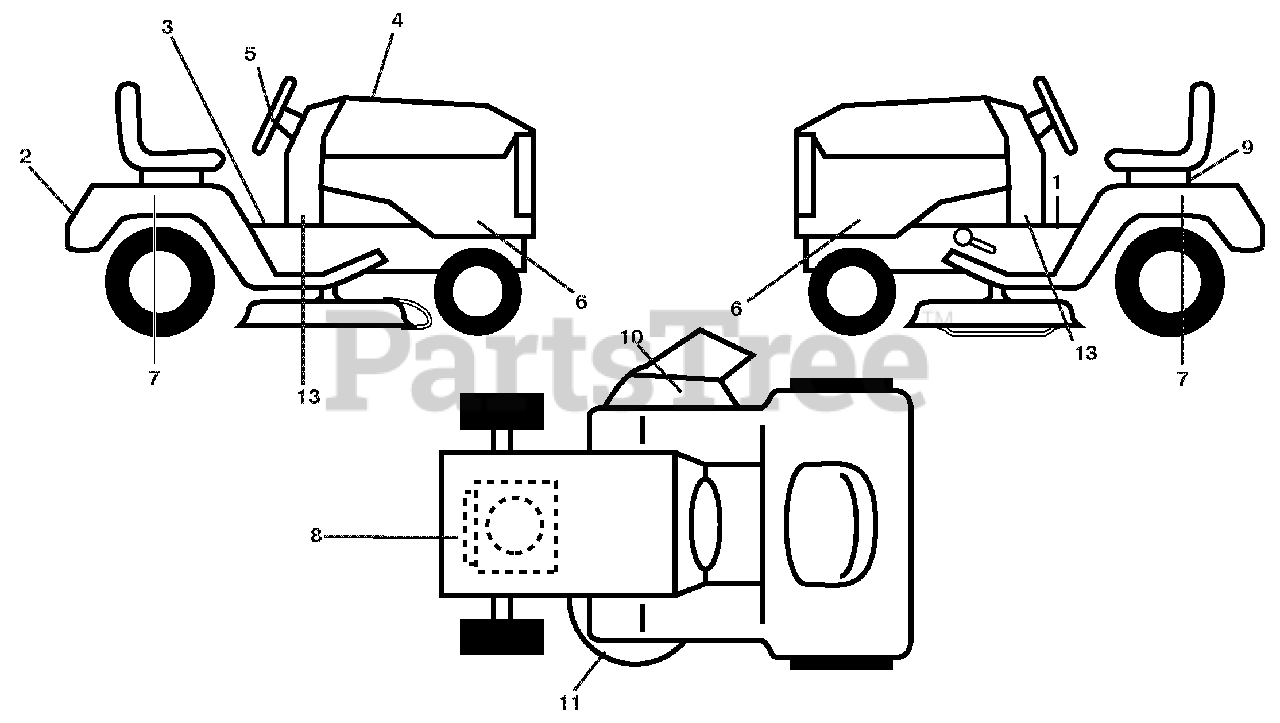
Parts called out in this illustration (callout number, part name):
1	DECAL.WARNING.START
2	DECAL.FENDER.REAR.ARIENS
3	DECAL.FENDER
4	DECAL.REPLACEMENT
5	DECAL.WHEEL.STEER.ARIENS
6	DECAL.SDPNL.PWRDBY B&S.ARIENS
7	DECAL.FENDER.SIDE.HYDRO
8	DECAL.ENGINE.HP
9	DECAL.BAT.DAN/POI P/L SYM.WPN
10	DECAL DECK/DEFLECT. WARNING
11	DECAL.V-BELT.SCH.
13	DECAL, DASH.LOWER
